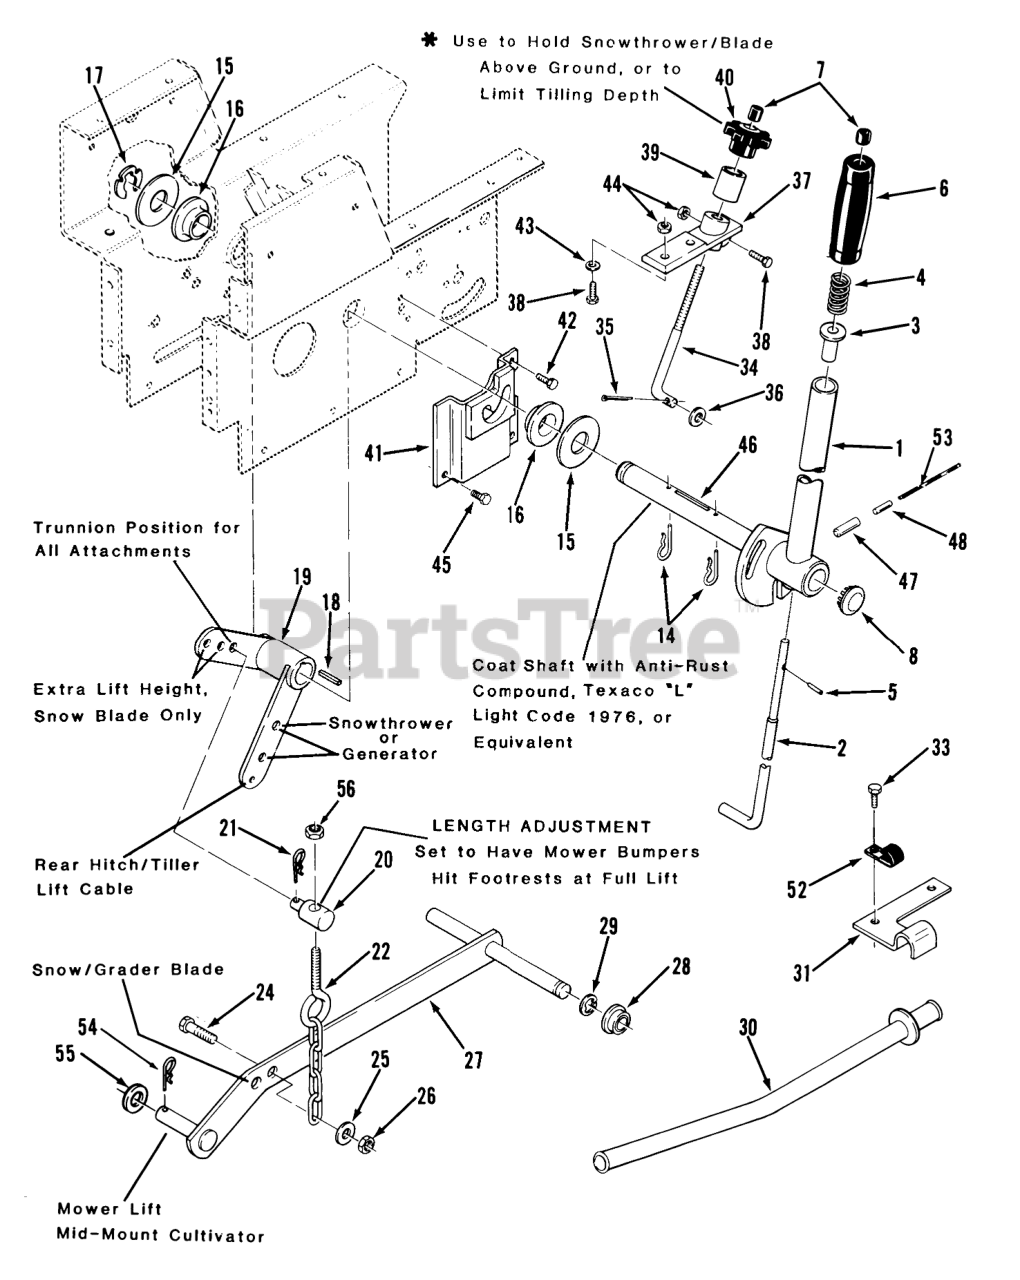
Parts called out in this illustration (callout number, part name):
1	Lift Lever (Includes Items 46, 47, 48)
2	ROD-LATCH LIFT
3	RETAINER-SPRING
4	SPRING-COMPRESSION
5	PIN-SPIROL
6	HANDGRIP
7	CAP-ROD, PLUNGER
8	PLUG
14	Pin-Cotter
15	WASHER
16	BEARING-FLANGE
17	Retainer
18	KEY-SQUARE
19	Bellcrank
20	TRUNNION-LIFT
21	Hairpin
22	CHAIN-LIFT
24	Bolt
25	WASHER 5/16 SAE
26	Nut
27	Bar-Lift
28	BUSHING
29	E Ring
30	TUBE ASSY COMPLET R
31	CLAMP-CONDUIT R
33	BOLT
34	ROD-HEIGHT CONTROL
35	Pop Rivet
36	Washer, 7/16
37	Casting
38	Bolt
39	Sleeve
40	KNOB-LIFT CONTROL
41	Latch Bracket
42	SCREW
43	WASHER 5/16 SAE
44	Nut
45	Bolt
46	SHAFT-LIFT LEVER
47	SPIROL PIN
48	Roll Pin
49	Roll Pin
52	CLIP
53	Lock Wire
54	Hairpin Cotter
55	Washer
56	NUT
